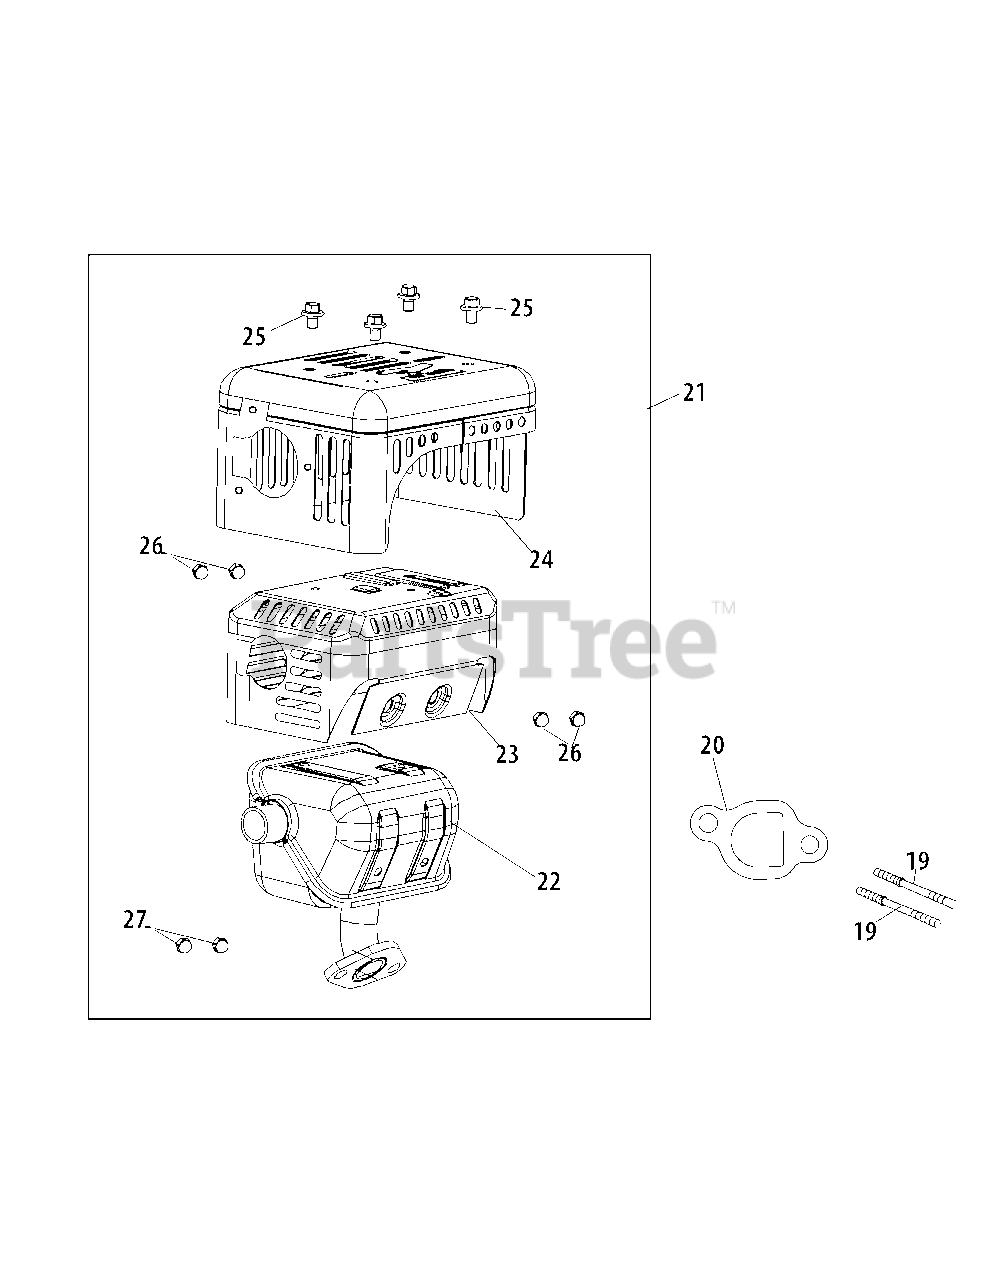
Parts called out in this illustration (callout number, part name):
19	Stud M8×34
20	Exhaust Pipe Gasket
21	Muffler Assembly
22	Muffler Body
23	Muffler Shield
24	Muffler Guard
25	Bolt M5×8
26	Bolt M5×12
27	Nut, M8
